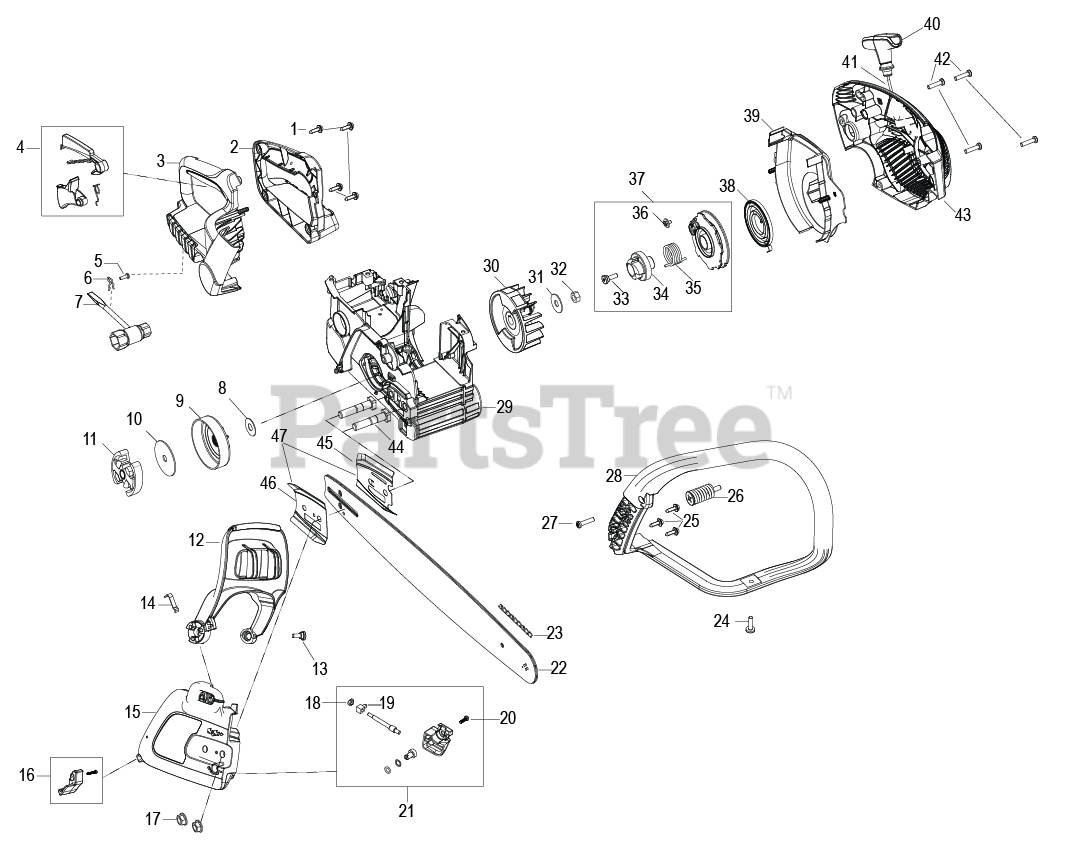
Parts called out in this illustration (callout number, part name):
1	Screw-Throttle Hsg.
2	REAR HANDLE COVER
3	REAR HANDLE
4	KIT TRIGGER & LOCKOUT YELLOW
5	SCREW 6-19X.437
6	SCRENCH RETAINER
7	WRENCH
8	WASHER
9	CLUTCH DRUM ASSY
10	FRICTION DISC,CLUTCH 36/41
11	CLUTCH ASSY
12	HANDGUARD
13	BOSS SCREW
14	Spring-Handguard
15	CHAINBRAKE
16	WEAR PROTECTOR KIT
17	Nut - Bar Mounting
18	SLEEVE
19	PAWL
20	SCREW
21	BAR ADJ KIT
22	BAR
23	CHAIN
24	Screw-Throttle Hsg.
25	Screw-Throttle Hsg.
26	CYLINDER SPRING ASSY
27	SCREW M5.38-14X22.225MM
28	HANDLE, FRONT
29	CHASSIS ASSY
30	FLYWHEEL FENGLONG-SAS 95280226
31	Washer #10 -14 - Flywheel
32	Nut- Flywheel
33	Screw-Shoulder
34	STARTER HUB
35	SPRING HUB EPS
36	Screw (Incl. in Starter Pulley Kit)
37	EPS STARTER KIT
38	SPRING
39	BAFFLE
40	HANDLE
41	Rope Kit
42	SCREW M5.38-14X22.225MM
43	STARTER HSG
44	BAR BOLT 36/41
45	GUIDE PLATE
46	GUIDE PLATE
47	KIT PLATE CHAIN GUIDE
